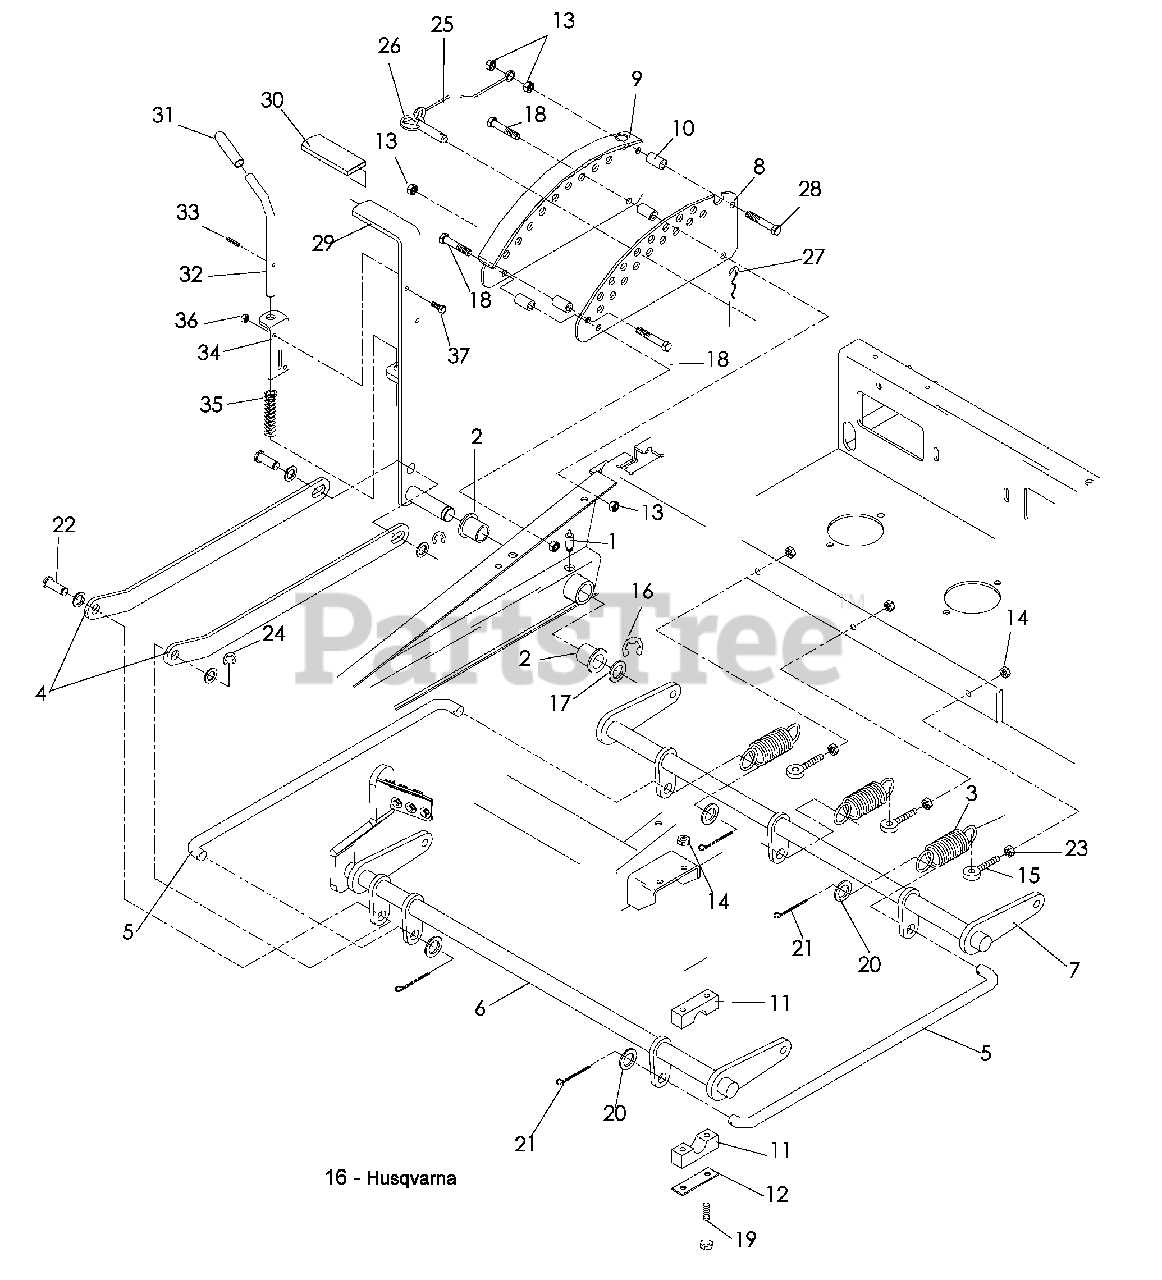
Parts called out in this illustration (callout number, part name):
1	ZERK, LONG
2	BUSHING, FLANGE
3	SPRING, DECK LIFT
4	LINKAGE, LIFT
5	LINK, CONNECTING
6	SHAFT ASSM W/PEDAL, FT
7	SHAFT, REAR LIFT
8	PLATE, ADJUSTMENT
9	PLATE, ADJUSTMENT
10	SPACER, DECK LIFT
11	BLOCKS, PILLOW
12	PLATE, SUPPORT
13	NUT 3/8-16 HEX NYLOC
14	NUT 5/16-18 HEX NYLOC
15	EYEBOLT 5/16 RH x 19/16
16	E-RING 7/8
17	BUSHING, MACHINE
18	HCS 3/8-16 x 2½
19	HCS 5/16-18 x 2¾
20	WASHER 5/8 SAE
21	PIN, COTTER 5/32 x 1¼
22	PIN, CLEVIS 5/8
23	NUT 5/16-18 WHIZ
24	E-RING 5/8
26	PIN, HITCH
28	HCS 3/8-16 x 2¾
29	LEVER, LIFT
30	CUSHION, HANDLE
31	GRIP, VINYL
32	PIN, LOCKING
33	PIN, GROOVED
34	PIN MOUNT, UPPER
35	SPRING, COMPRESSION
36	NUT ¼-20 CENTERLOCK
37	HCS ¼- 20 x ¾
